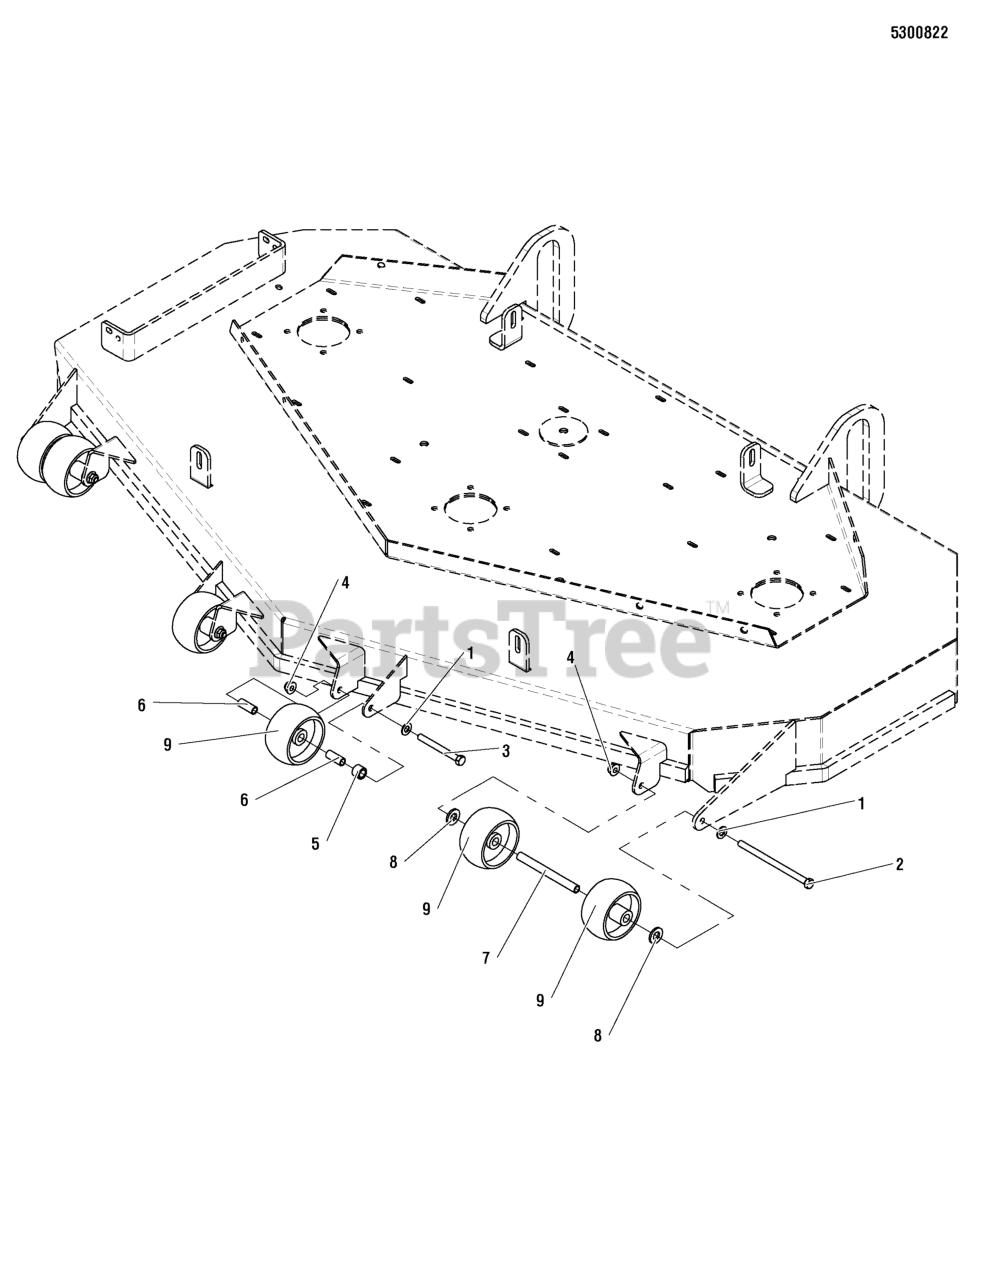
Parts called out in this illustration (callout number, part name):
1	WASHER, 3/8 SAE
2	BOLT, 3/8-16 X 6" GD5 CZ
3	BOLT, 3/8-16 X 3-1/2" GD5 CZ
4	NUT, 3/8-16 HEX NYLOCK FLANGE
5	SPACER, .51 X .75 X .56
6	SPACER, .38 X .50 X 1.25, CZ
7	SPACER, .38 X .50 X 5.06
8	WASHER, 1/2" GD9 YZ
9	WHEEL- 2.00 WIDE 3.88 DIA 0.531ID POLY
